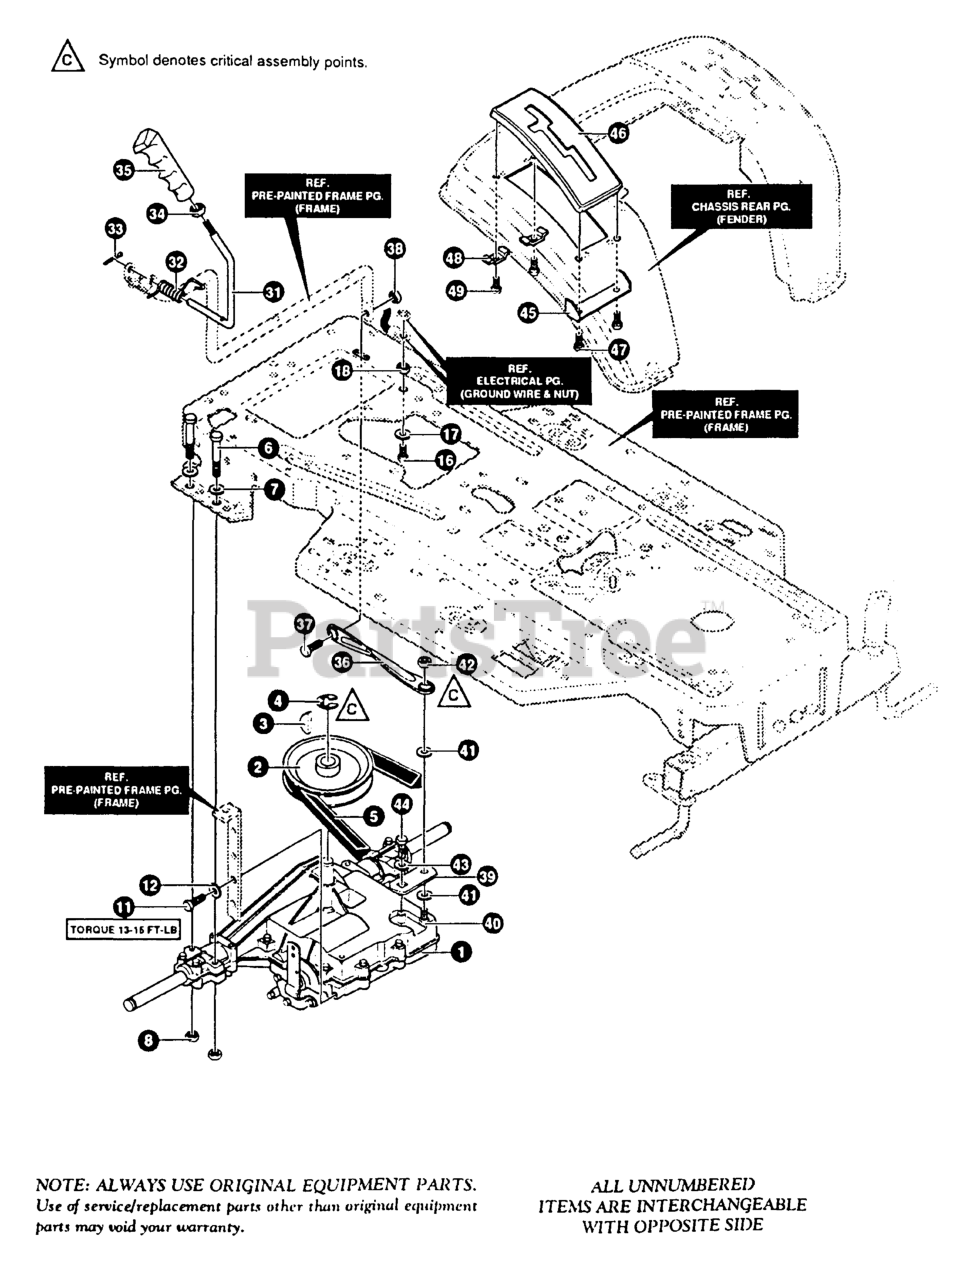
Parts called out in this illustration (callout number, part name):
1	TRANSAXLE, 2WS **
2	PULLEY, 6.6 OD
3	KEY, HI-PRO
4	RING, RETEX
5	BELT, V 41, 87.25
6	SCREW, 5/16-18 x 2.50
7	WASHER, FLAT .344 X .69 X .065
8	NUT, 5/16-18
11	SCREW, 5/16-18 x 0.75
12	WASHER, .328 X .60 X .09
16	SCREW, 5/16-18 x 0.75
17	WASHER, .320 X .61 X .03
18	NUT, 5/16-18
31	LEVER, SHUT UPPER
32	SPRING, TORSION
33	PIN, COTTER
34	NET, 1/2-13
35	HANDLE, 1/2-13
36	LINK, TIE ROD SHIFT
37	SCREW, 3/8-16 X 1.15
38	NUT, 3/8-16
39	BRACKET,SHIFT
40	SCREW, 3/8-16 X 1.25
41	WASHER, FLAT .406 X .81 X .065
42	NUT, 3/8-16
43	WASHER, .750 X .250
44	SCREW, 1/4-28 X .75
45	BRACKET COVER
46	COVER PLASTIC
47	SCREW, 1/4-15 X .44/.53
48	CLAMP, SPRING
49	SCREW, 1/4-15 X .44/.53
